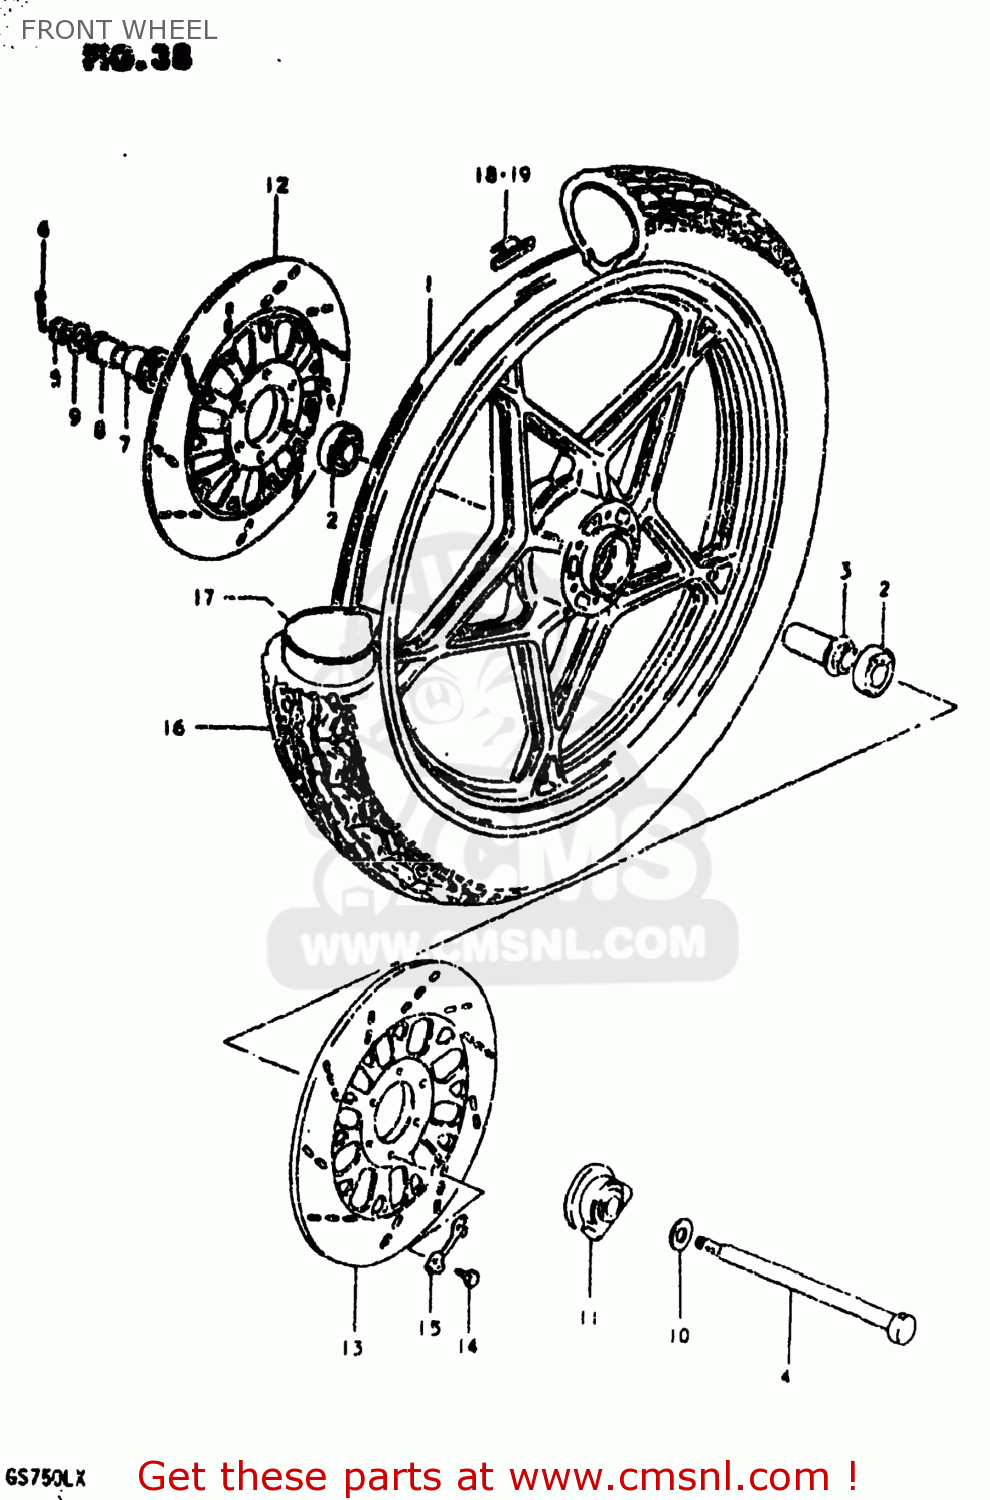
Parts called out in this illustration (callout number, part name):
1	FR CAST WHEEL 1
2	BEARING
3	SPACER,FR HUB BEARING
4	AXLE,FR
5	NUT 12MM
6	COTTER PIN
7	SPACER,FR AXLE,R
8	SPACER
9	WASHER
10	WASHER(15.5X26X2.3)
11	BOX ASSEMBLY,SPEEDOMETER GEAR
12	DISC,FR BRAKE,R
13	DISC,FR BRAKE,L
14	BOLT(8X25)
15	WASHER
16	TIRE,FRONT
17	TUBE 2.75-19 070-483MM
18	BALANCER,WHEEL
19	BALANCER,WHEEL
